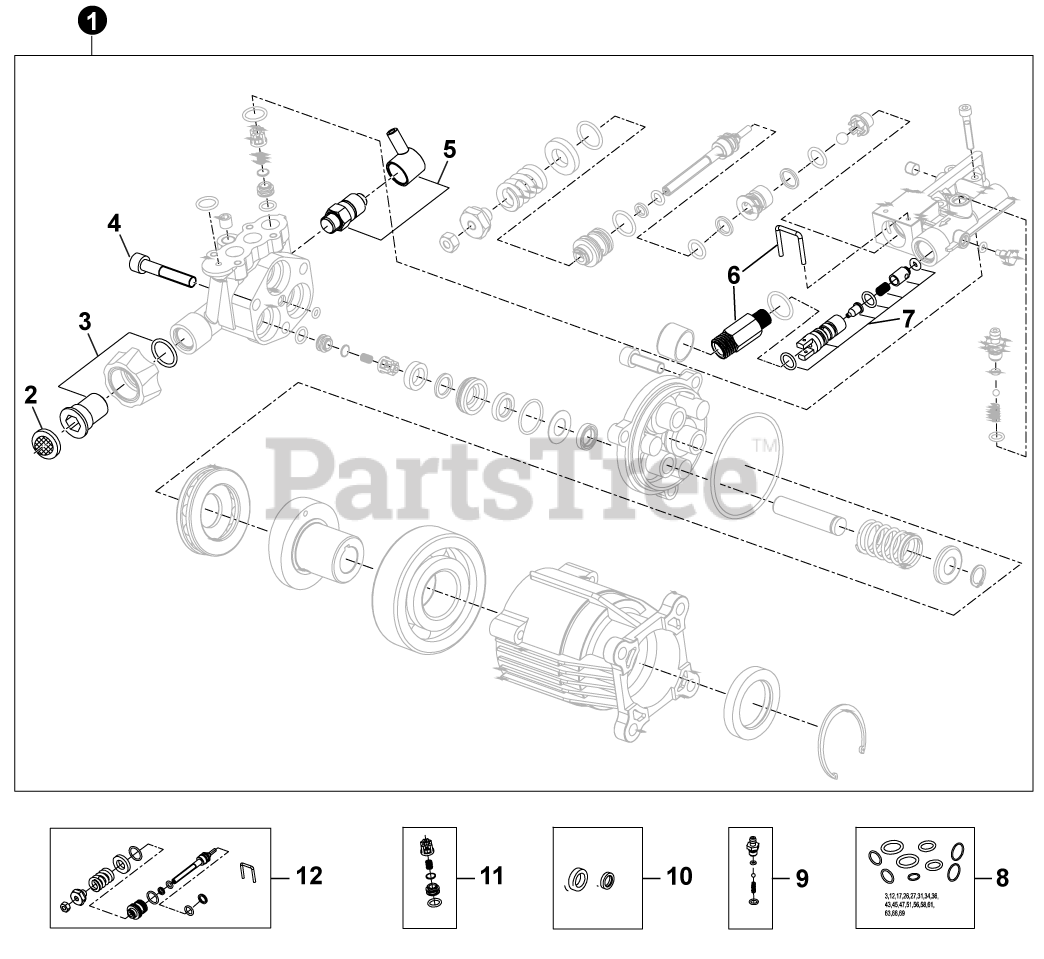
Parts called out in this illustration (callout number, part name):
1	PUMP ASSY
2	FILTER, INLET SCREEN
3	ADAPTOR, GARDEN HOSE INLET
4	BOLT, PUMP HEAD
5	VALVE, THERMAL RELIEF
7	VALVE, INLET CHECK
8	KIT, O-RING
9	KIT, INJECTOR
10	KIT, WATER SEAL
11	KIT, VALVE
12	KIT, UNLOADER
